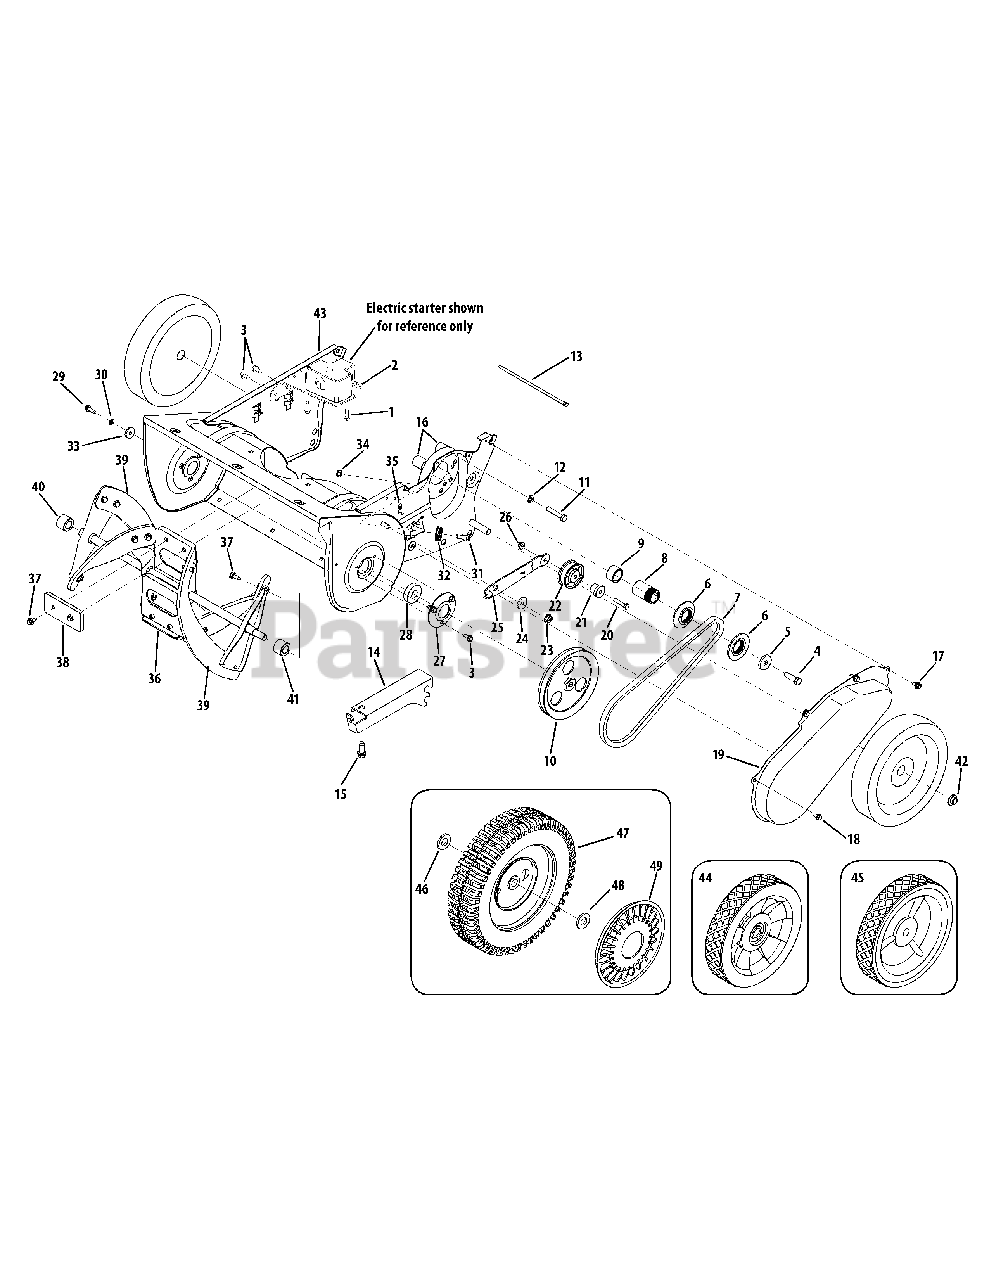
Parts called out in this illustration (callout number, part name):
1	Hex Screw, #12-16 x .75
2	Electric Starter Support Bracket
3	Hex Screw, 1.4-14 x .500
4	Hex Screw, 3.8-24 x 1.25
5	Flat Washer, .406 x 1.25 x .157
6	Pulley Half, 4L-V x 2.30
7	V-Belt
8	Spacer, .875 x 1.185
9	Spacer, .88 x 1.18 x .74
10	V-Type Pulley, 1.2 x 35.7
11	Hex Screw, 5.16-24 x 1.75
12	Lock Washer, 5.16
13	Cable Tie, 7.5
14	Engine Support Bracket
15	Hex Washer Screw, 3.8-16 x 1.000
16	Spacer, .875 x .320 x 1.027
17	Hex Washer Screw, 1.4-14 x .625
18	Hex Washer Screw, 1.4-20 x .375
19	Belt Cover - Red
19	Belt Cover - Gray
20	Hex Screw, 1.4-20 x 1.25
21	Shoulder Spacer, .260 x .785 x .538
22	Pulley Assembly, 1.917
23	Flange Lock Nut, 5.16-18
24	Shoulder Spacer
25	Idler Bracket w/ Brake
26	Flange Lock Nut, 1.4-20
27	Bearing Cup
28	Ball Bearing, 1.25 x 37 x 12.6301
29	Hex Screw, 1.4-20 x .750
30	Lock Washer, 1.4
31	Shoulder Screw, .340 x .335 x 1.4-28
32	Cable Roller
33	Flat Washer, .265 x .938 x .120
34	Hex Lock Nut, 1.4-28
35	Extension Spring, .33 x 1.12
36	Auger Assembly, 21inch
37	Hex Screw, 1.4-14 x .625
38	Rubber Pad
39	Spiral Crescent
40	RH Spacer
41	LH Spacer
42	Push Cap, 1.2
43	Auger Housing - Red
43	Auger Housing - Gray
44	Wheel, 7 x 1.5 - Gray
45	Wheel, 7 x 1.61- White
46	Flat Washer, .510 x 1.000 x .125
47	Wheel, 9 x 2.125
48	Flat Washer, .53 x .93 x .050
49	Hub Cap
